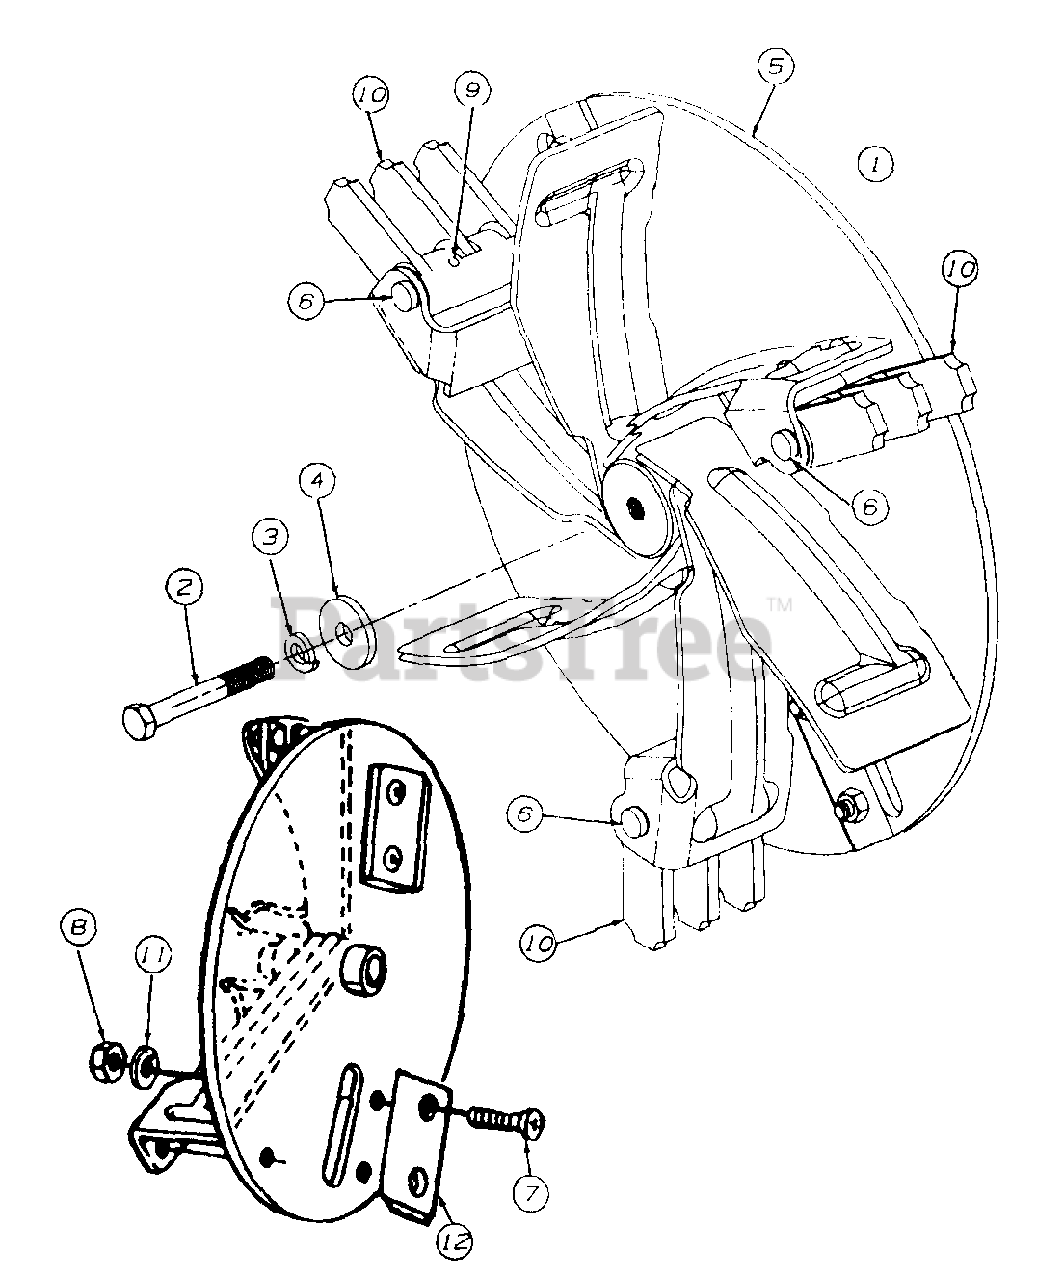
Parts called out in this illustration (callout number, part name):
1	IMPELLER ASSY COMP.
2	SCREW-HEX
3	WASHER-LOCK
4	WASHER-FLAT
5	IMPELLER ASSY
6	PIN-CLEVIS
7	SCREW-FLAT HEAD
8	NUT-HEX LOCK
9	PIN-ROLL SPRING
10	BLADE-FLAIL
11	WASHER-LOCK
12	BLADE-CHIPPER
